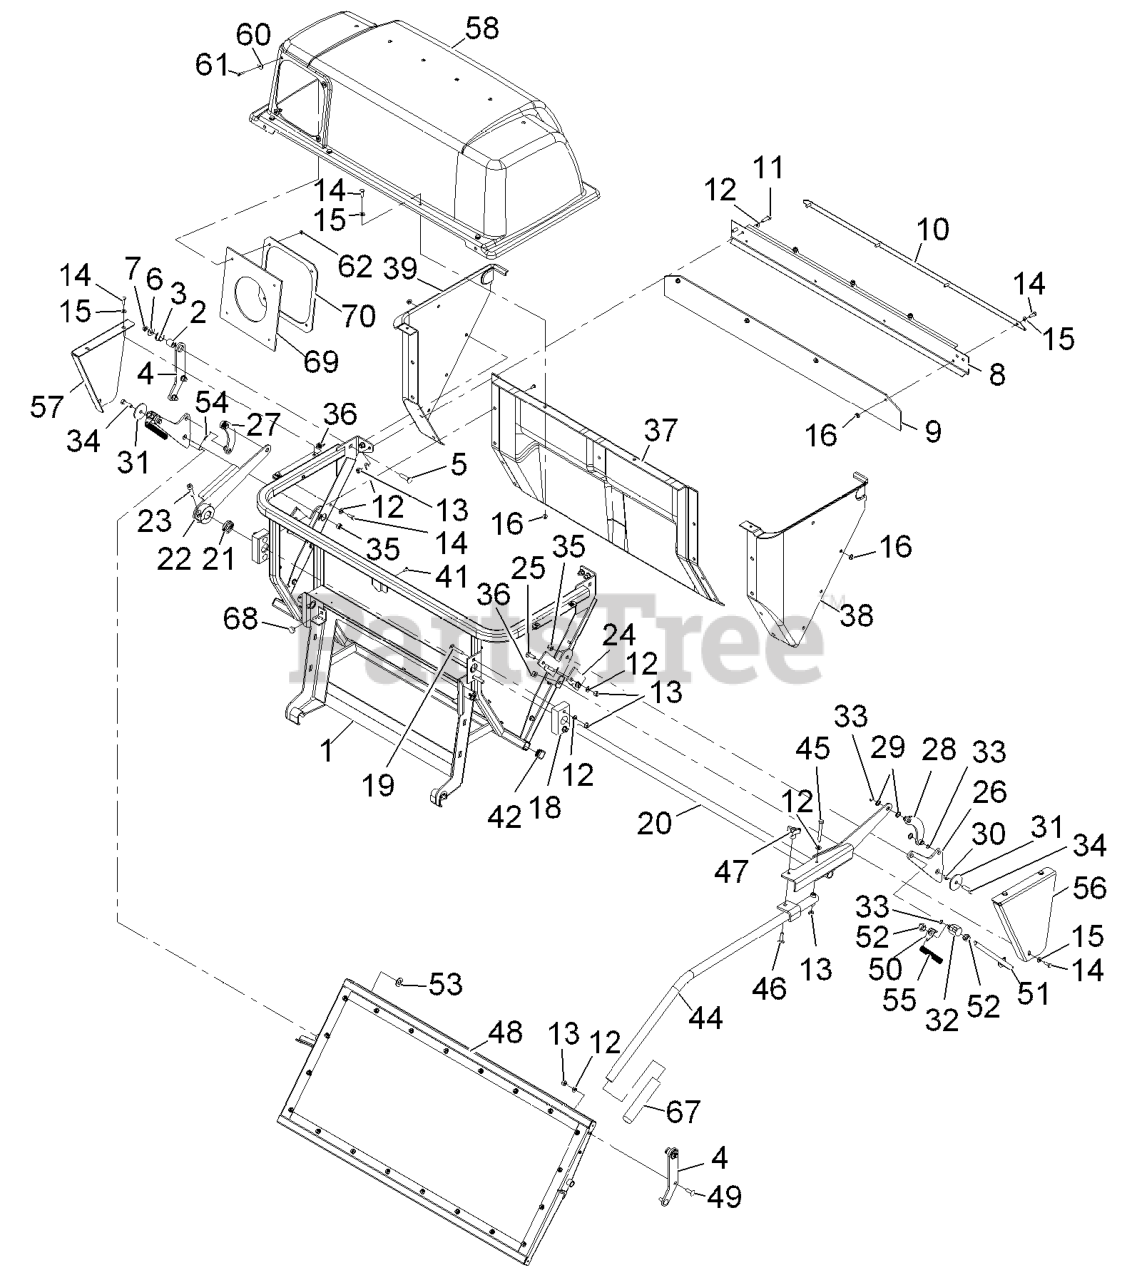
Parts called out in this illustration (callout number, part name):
1	FRAME ASM
2	PIN-PIVOT, HINGE
3	BEARING
4	PLATE-HINGE
5	SCREW-CARR
6	WASHER-FLAT
8	PLATE-REAR
9	SEAL-DOOR
10	STRAP-HOLD DOWN
11	SCREW-HH
12	WASHER-PLAIN
13	NUT-LOCK, NI
14	SCREW-HH
15	WASHER-FLAT
18	BEARING
19	BOLT-CAR
20	BELLCRANK
21	SHAFT-COLLAR
23	SCREW-HSH
24	STOP-LINKAGE
25	BOLT-CARR
26	ARM-LINKAGE, DOOR
27	LINK-RH
28	LINK-LH
29	WASHER-NYLON
30	BEARING-LINKAGE, PIVOT
32	TRUNNION-LINK
33	RING-RETAINING
34	SCREW-HH
35	NUT-LOCK, NI
36	Nut-Retainer-Panel 1/4-20
37	PANEL-BAGGER
38	PANEL-BAGGER, LH
39	PANEL-BAGGER, RH
41	RIVET-BLIND
44	HANDLE-QD7
45	SCREW-HH
46	Bolt-Carriage 5/16-18 X 1 1/4
47	KNOB-3 PRONG
48	Asm, Door
49	SCREW-CARR
50	ANCHOR-SPRING
51	LINK-DOOR
52	NUT-HEX
53	WASHER-FLAT
54	PIN-COTTER
58	ASM, HOOD
60	WASHER-FLAT
61	SCREW-PPH
62	NUT-LOCK, NI
67	HANDLE-GRIP
69	SEAL-CHUTE
70	CLAMP-SEAL
